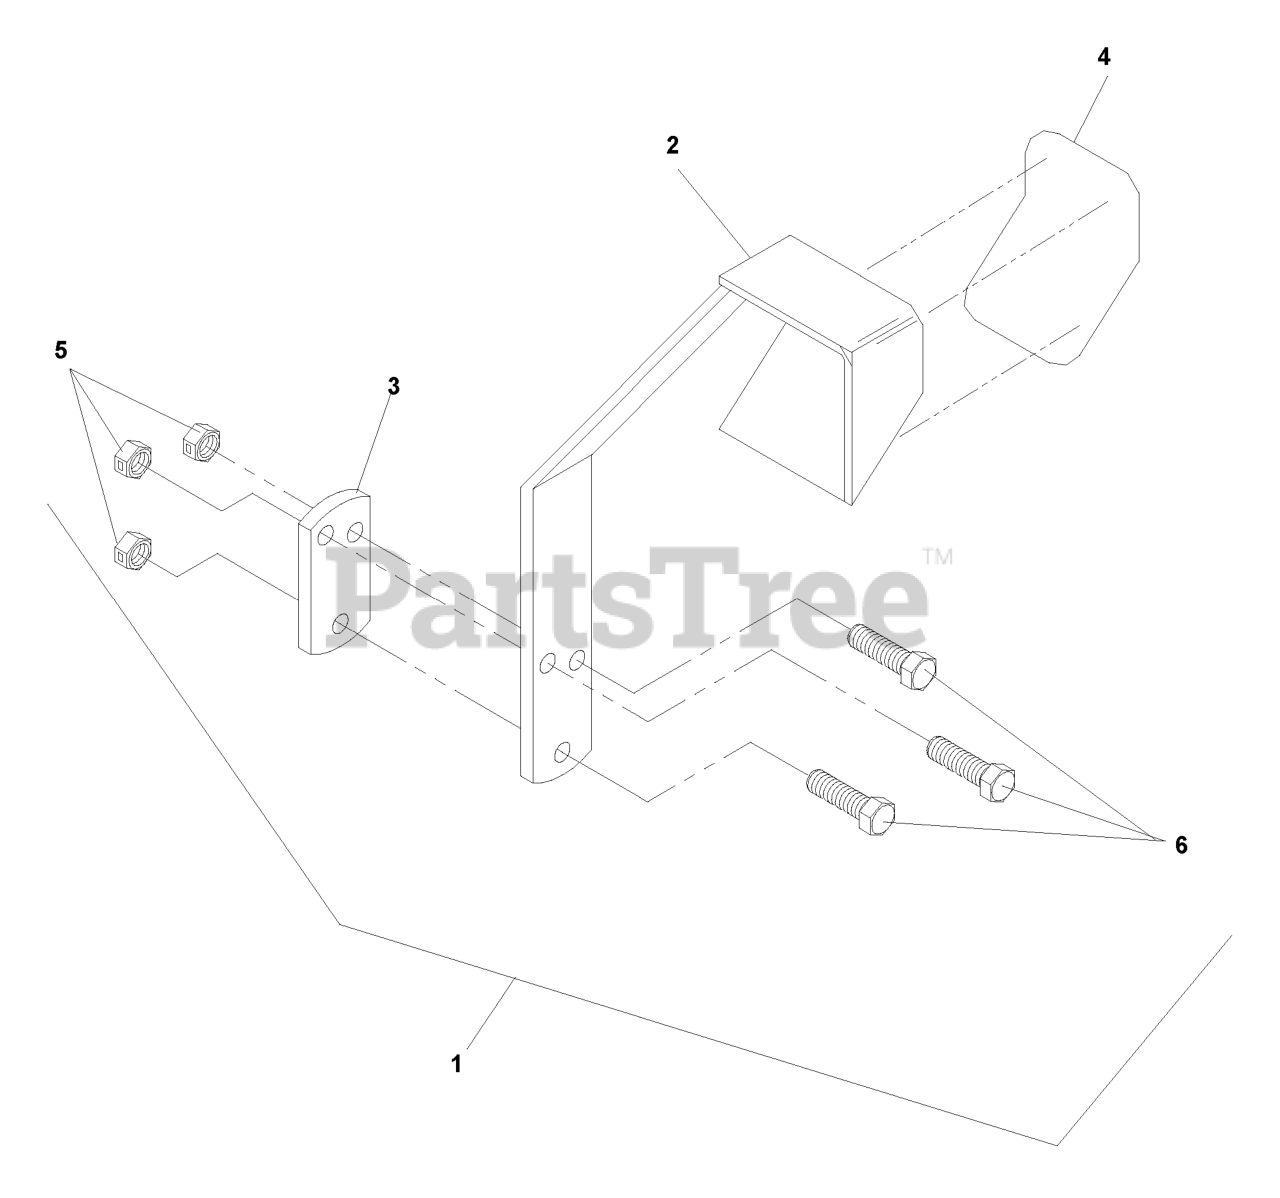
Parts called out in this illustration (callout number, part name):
1	FOOT ASSIST DECK LIFT-GEN II
2	LIFT PEDAL BLK
3	TIGHTENING PLATE BLK
4	ANTI-SKID PAD
5	NUT 3/8-16 NYLOC
6	HCS 3/8C X 1 1/2
